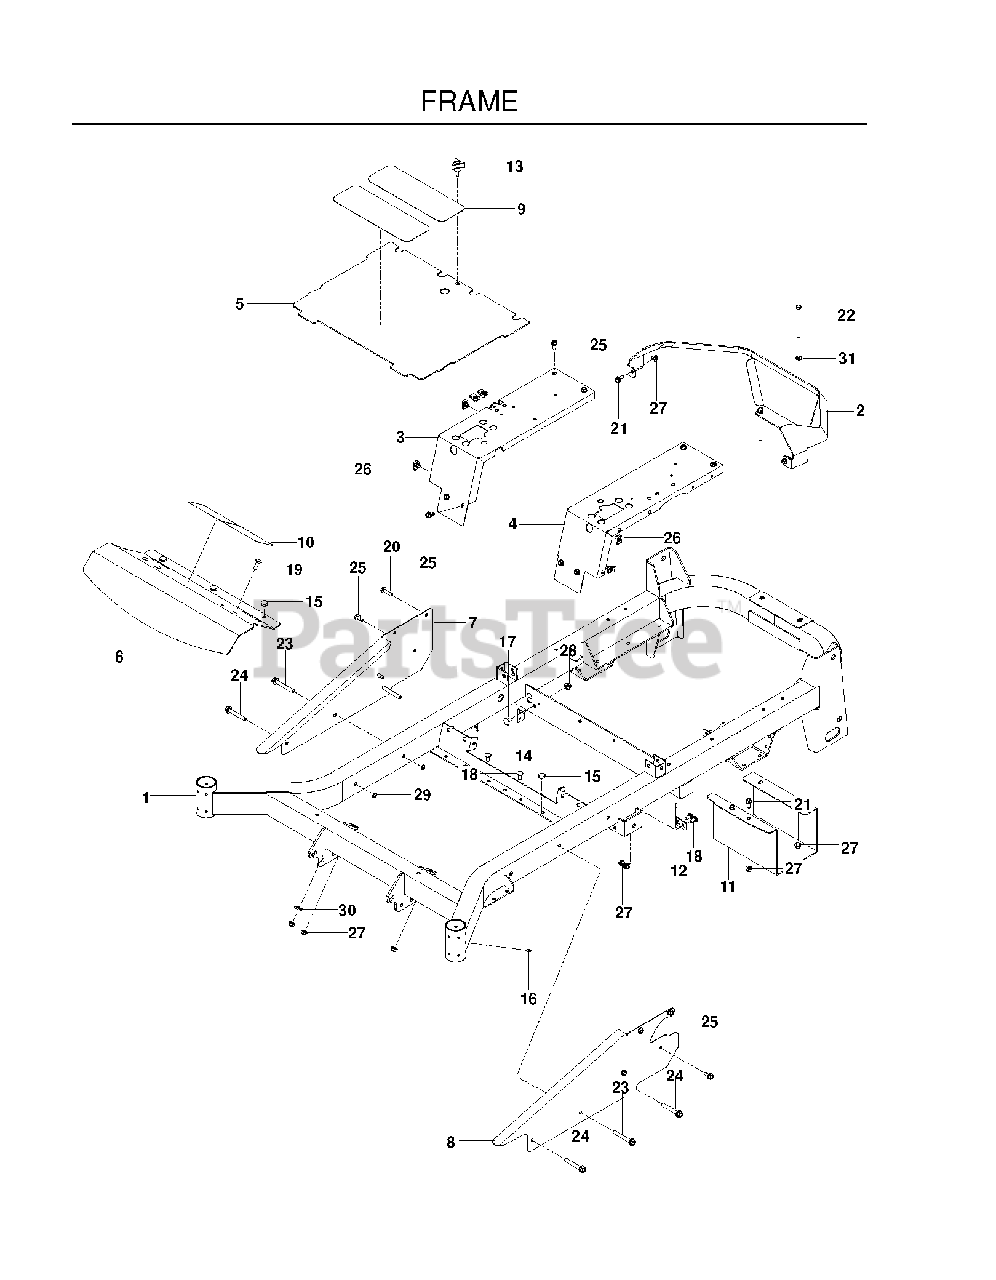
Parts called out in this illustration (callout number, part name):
1	FRAME W/DECALS
2	GUARD, REAR MZ, GRAY
3	PANEL, FILLER LT, ORG
4	PANEL.FILLER.RT.ORNAGE
5	PLATE, FLOOR W/DECALS
6	PLATE, FOOTREST
7	SIDE.RT.ORANGE
8	SIDE.LT.ORANGE
9	ANTI-SKID PAD
11	SHIELD.MUFFLER.BLACK
12	STOP, DECK, EZ+
13	KNOB W/STUD
14	BRACKET.DAMPENER.BLACK
15	GROMMET, BUMPER
17	RHSNB 3/8-16 X 3/4 GR 5 BLK ZN
18	BOLT 5/16C X 3/4" CARRIAGE
19	RHSNB 5/16C X 1
20	HHFS 5/16-18 X 1.25 TPBLT GD 5
21	HHFS 5/16-18 X 3/4
22	HCS 5/16C X 4
23	HHFS 3/8-16 X 2 3/4
24	HHFS 3/8-16 X 2.5 GR 5 ZD
25	BOLT 5/16-18 X 3/4
26	U-CLIP 5/16-18 NUT RETAINER
27	5/16-18 NYLOC FLANGE NUT
28	NUT 3/8-16 HEX FLG NYLOC ZD
29	NUT HEX 3/8-16 NYLON, THIN
30	WASHER 1/2" FLAT
31	FLAT WASHER 5/16 SAE
